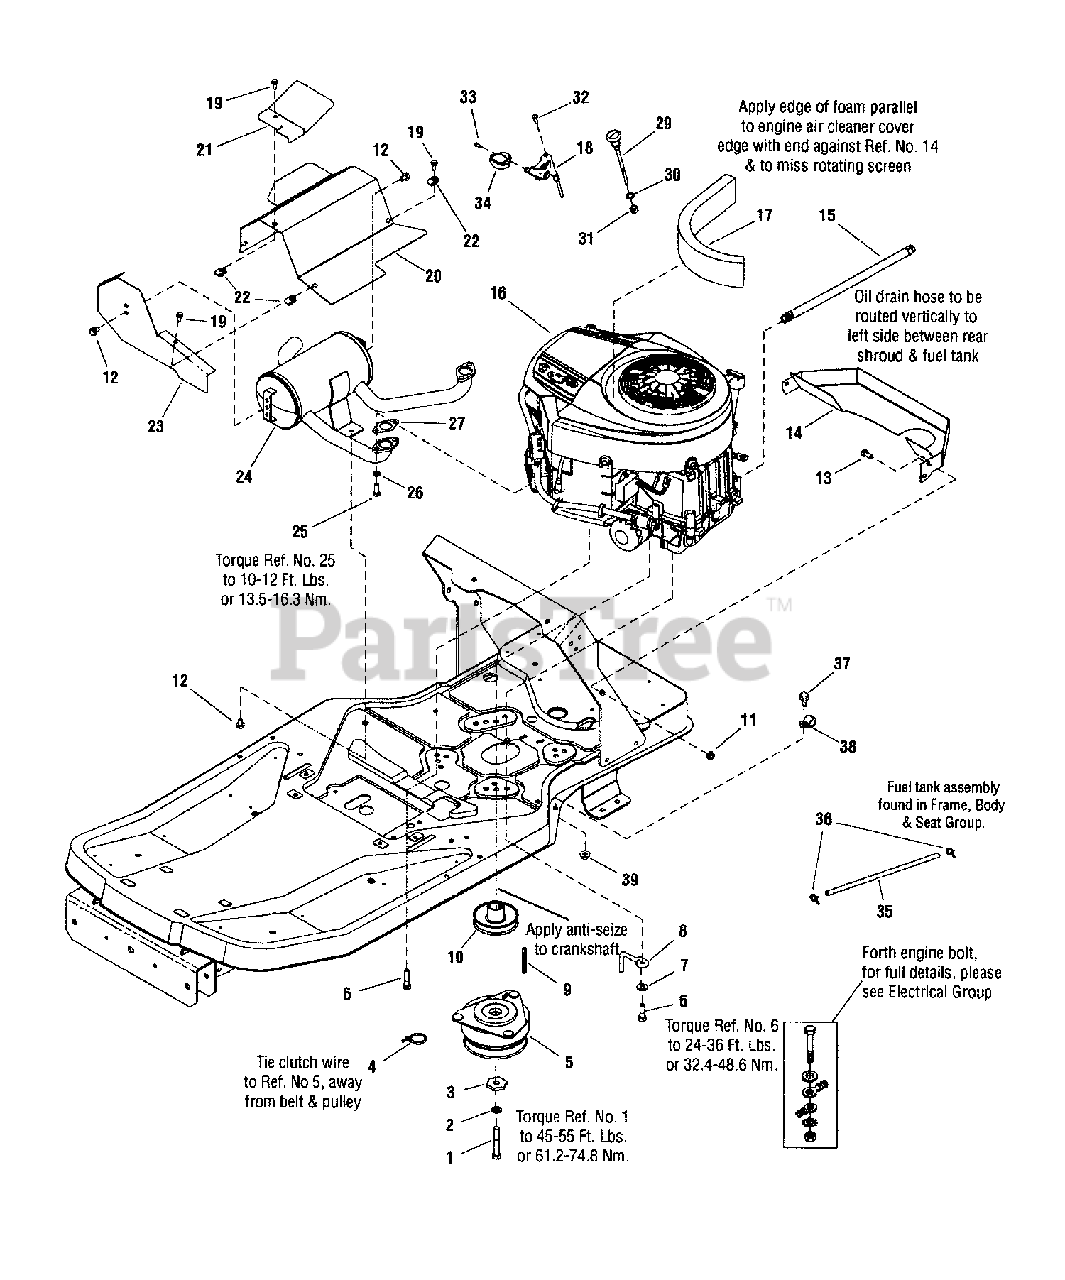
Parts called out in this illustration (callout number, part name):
1	SCREW, 7/16-20 x 3" Hex Head Cap, GR5 (w/Nyloc Patch)
2	LOCKWASHER, Spring, .438
3	WASHER, Hex, .453 I.D. x 1-1/2"
4	TIE, Self Locking 3-5/8" Long
5	CLUTCH, Ogura JD-11
6	SCREW, 3/8-16 x 1-1/4" Hex Washer Head Taptite
7	WASHER, 3/8", (.41 I.D. x .87 O.D. x .08 Thick)
8	RETAINER, Clutch
9	KEY, .250 Square x .91 Long Parallel
10	PULLEY, Engine- ZT
11	NUT, 5/16-18 Hex Whiz Lock Flange
12	SCREW, 5/16-18 x 1/2" Hex Washer Head Taptite
13	SCREW, 5/16-18 x 3/4" Hex Head Cap, Black
14	AIR DUCT, Inlet
15	HOSE, Oil Drain, 16-1/2" Long
17	SEAL, Foam Air Inlet
18	CONTROL, Throttle, .187 Cable 18.80 Long
19	SCREW, 1/4-20 x 5/8" Hex Whiz Lock Flange
20	HEAT SHIELD, Muffler Top
21	HEAT SHIELD, Throttle
22	NUT, Speed, 1/4-20
23	HEAT SHIELD, Muffler Side
24	MUFFLER, 24 HP V-Twin ELS
25	SCREW, 5/16-18 x 3/4" Hex Head Cap, GR8
26	LOCKWASHER, Spring 5/16" Black
27	GASKET, Exhaust B&S
29	CABLE, Choke, 20" Long
30	WASHER, 3/8" Internal Tooth Lock
31	NUT, 3/8-24 Hex
32	SCREW, 1/4-20 x 5/8" Pan Head Taptite Torx
33	SCREW, #10-16 x 3/4" Pan Head Taptite Combo
34	KNOB, Throttle, Red
35	** HOSE, Fuel, Low Perm, 1/4" I.D. x 19-1/2" Long
36	CLAMP, Fuel Hose
37	SCREW, 5/16-18 x 3/4" Hex Flange Lock
38	CLIP, Harness, 5/8"
39	NUT, 5/16-18 Hex Whiz Lock Flange
